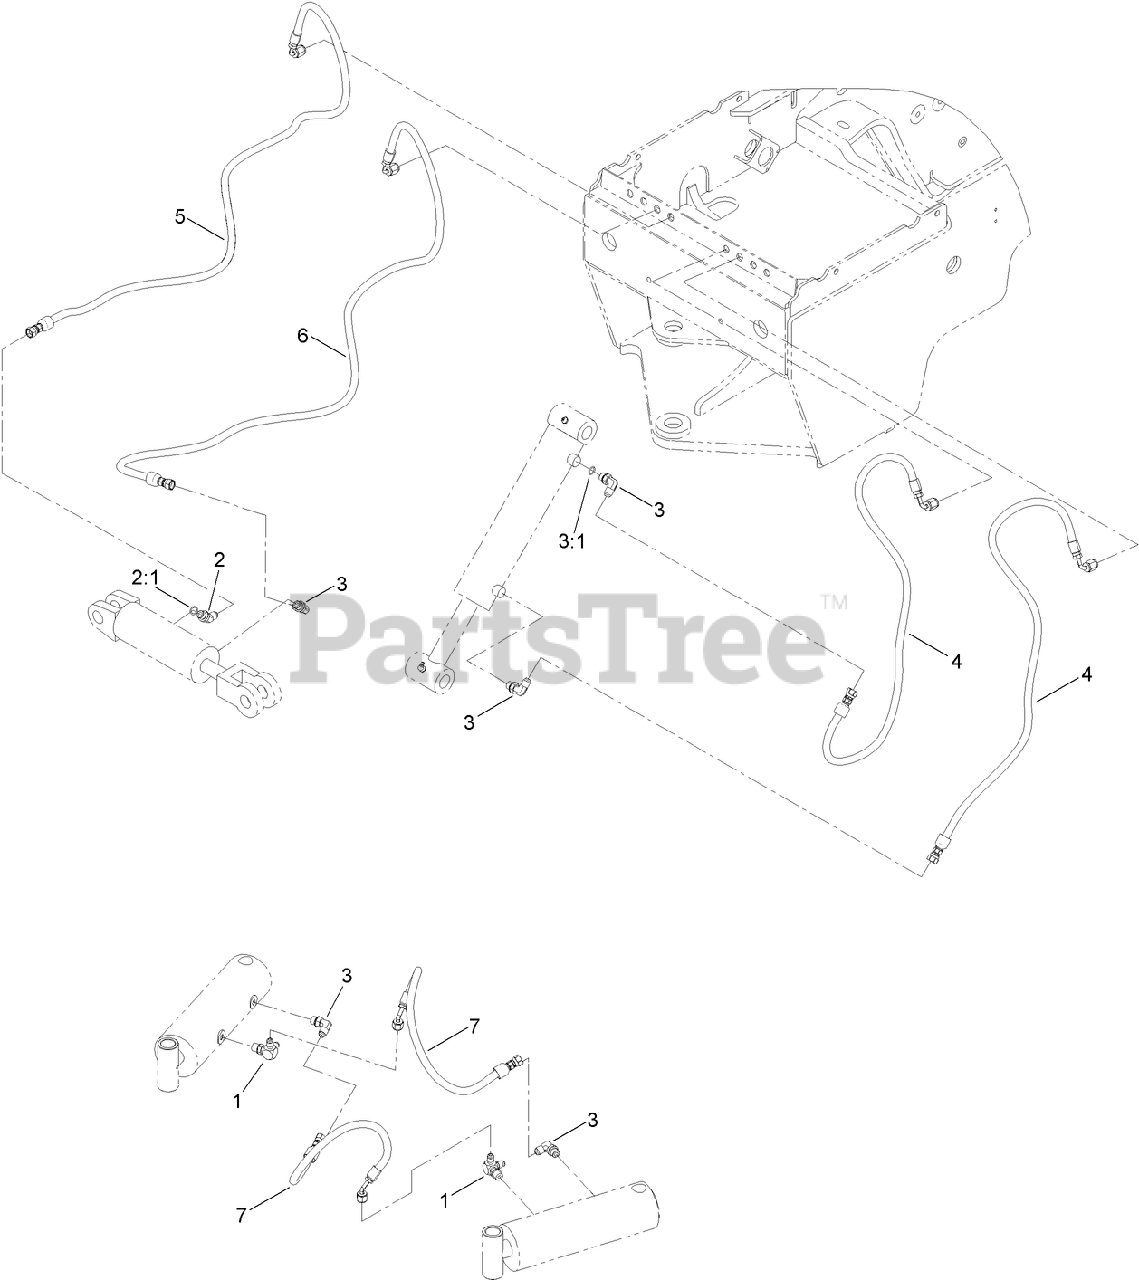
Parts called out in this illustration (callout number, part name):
1	FITTING
2	FITTING-ELBOW, 45 DEG
2:1	O-RING
3	FITTING-ELBOW, 90 DEG
3:1	O-RING
4	HOSE ASM
5	HOSE ASM
6	HOSE ASM
7	HOSE ASM
